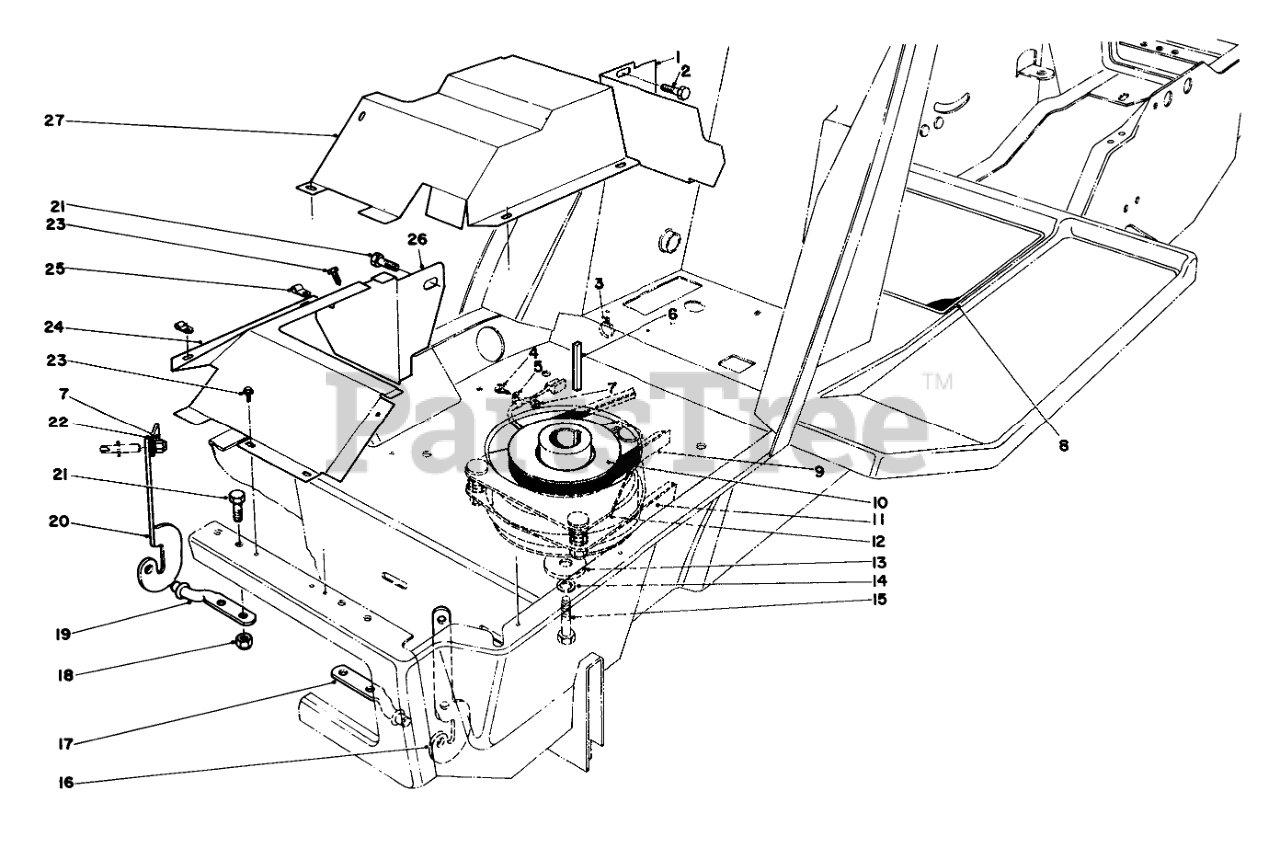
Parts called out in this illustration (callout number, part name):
1	EXH SHIELD SUPT B
2	SCREW-HH
3	TIE-MOUNT, PUSH
4	SCREW-HH
5	CLAMP
6	KEY-SQUARE
7	NUT-LOCK, CONE
8	OPERATION DECAL
9	V BELT
10	Pulley
11	V-BELT, ENG/DECK
12	Clutch Assembly-Deck
13	WASHER-CLUTCH
14	WASHER-LOCK
15	SCREW-HH
16	Bracket-Hinge L.H.
17	LIGHT SWITCH
18	NUT-LOCK, CONE
19	Hinge Pin-Hood R.H.
20	RH HINGE BRKT
21	SCREW-HH
22	SCREEN SUPT BRKT
23	SCREW-HWHTF
24	Heat Shield
25	CABLE CLAMP
26	Support Heat Shield
27	HINGE-DOOR, BAG
